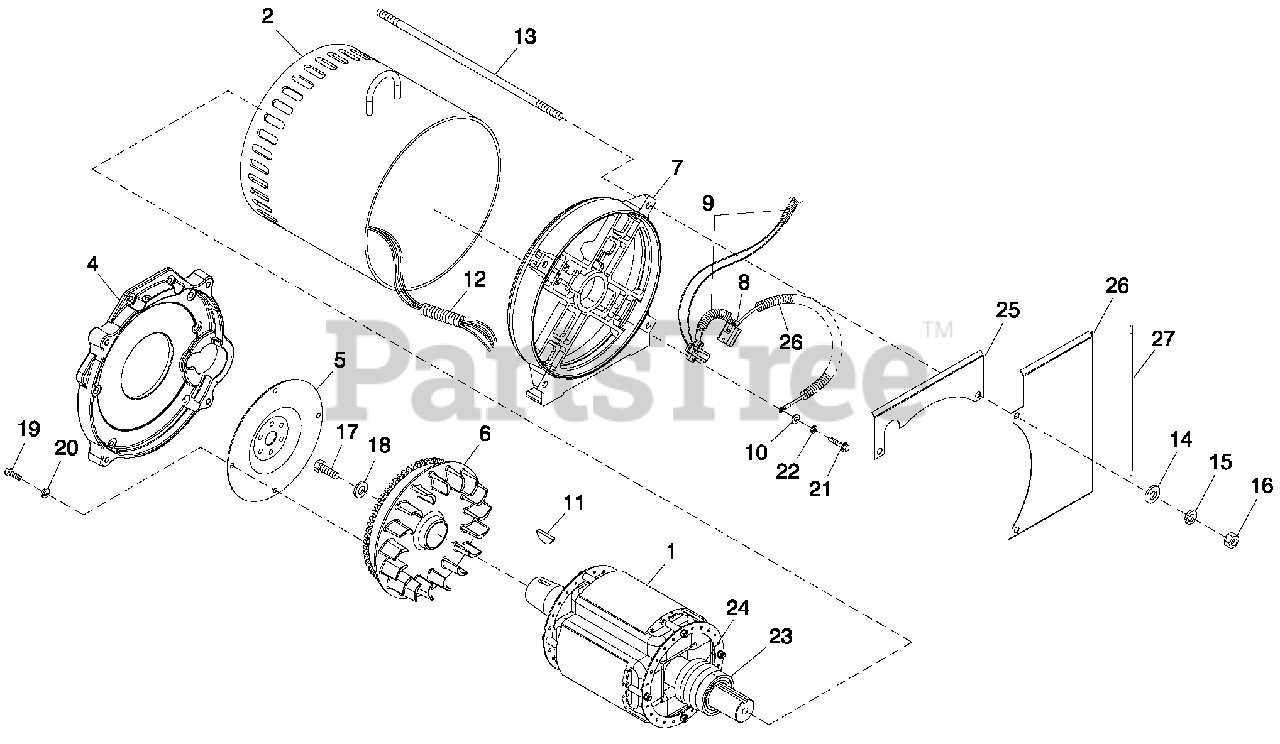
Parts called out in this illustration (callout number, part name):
1	RTR 390 45AD1 CPL
2	STR 390 45AD1 CPL
4	ENGINE ADAPTER
5	FLEXPLATE
6	ASSY FLYWHEEL CPL W/40MM FAN B
7	REAR BEARING CARRIER 390/DRCT
8	ASSY BRUSH HOLDER 390/HSB
9	CONDUIT FLEX .38" ID (60" )
10	WASHER FLAT #8 ZINC
11	KEY WOODRUFF #E
12	CONDUIT FLEX 1.0" ID (35" LG)
13	STUD M 14-2.0 570 G5 ZINC
14	WASHER FLAT M14
15	WASHER LOCK M14
16	NUT HEXM14-2.0G8YEL CHR
17	SCREW HHCM16-2.0X 45 G8.8
18	SPACER .69 X 2.75 X .37 ST/ZNC
19	SCREW HHC M10-1.50 X 16 G10.9
20	WASHER LOCK M10
21	SCREW HHTT M4-0.7X 25 BP
22	WASHER LOCK #8-M4
23	BALL BEARING-45 MM
24	SLIP RING MACHINED
25	GUARD REAR BEARING CARRIER
26	GUARD REAR BEARING CARRIER
27	TRIM VINYL BLACK 1/8GP (16.5" LG)
